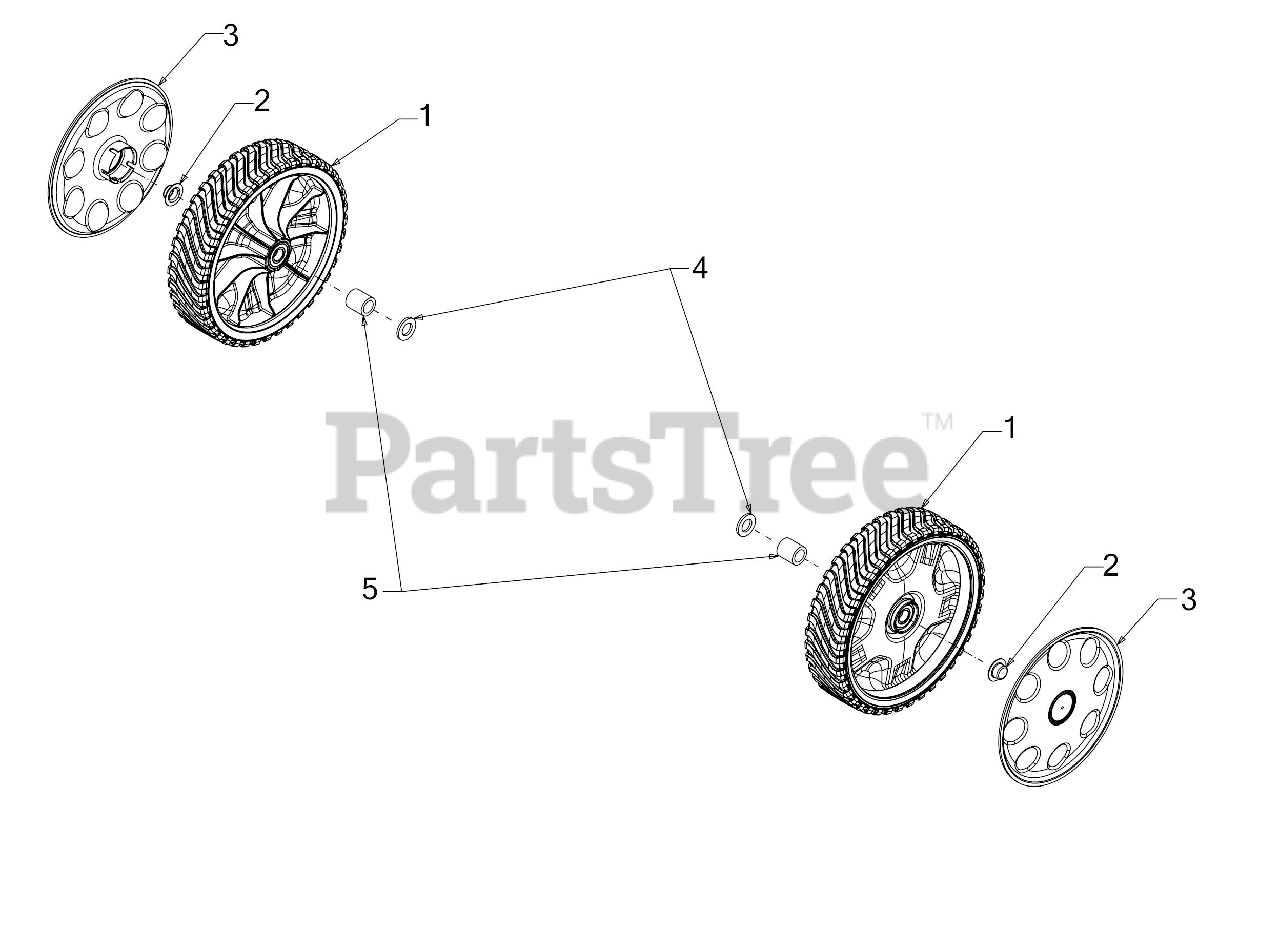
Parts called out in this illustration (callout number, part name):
1	WHEEL ASSEMBLY (8 x 2)
4	FLAT WASHER .535 x .930 x .090
5	SPACER .525 x .775
